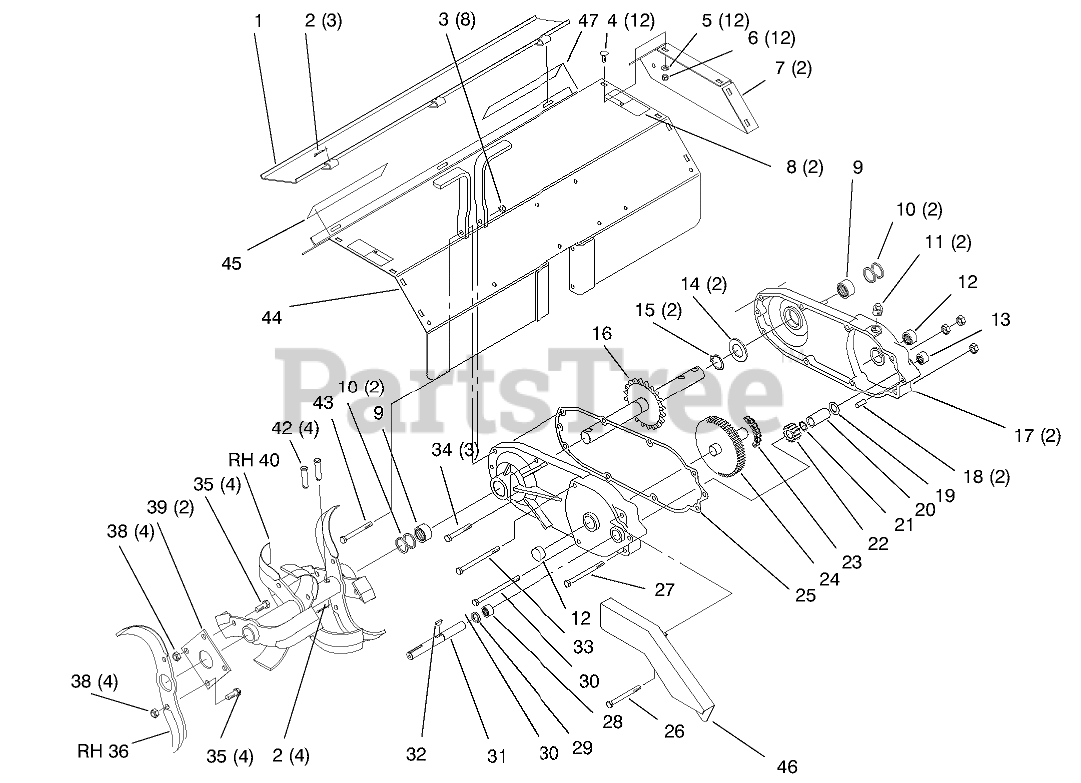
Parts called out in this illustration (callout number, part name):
1	GUARD ASM
2	PIN-COTTER
3	NUT-LOCK, NI
4	BOLT-CARR
5	WASHER-PLAIN
6	NUT-LOCK, NI
7	COVER-TINE END
8	DECAL-DANGER
9	BEARING-NEEDLE
11	PLUG-PIPE, SQH
12	BEARING-NEEDLE
13	BEARING-NEEDLE
14	WASHER
15	RING-RETAINING
16	TINE SHAFT ASM
17	GEAR CASE TILLER RED
18	PIN-ROLL
19	WASHER-THRUST
20	TUBE-SPACER
21	Ring-Snap
22	GEAR-PINION
23	CHAIN
24	GEAR AND SHAFT ASM
25	GASKET-TRANSMISSION
26	SCREW-HH
27	SCREW-HH
28	BEARING-NEEDLE
29	SEAL-OIL
30	SCREW-HH
31	SHAFT-INPUT
32	KEY-WOODRUFF
33	SCREW-HH
34	SCREW-HH
35	SCREW-HH
36	TINE-RH
37	TINE-LH
38	NUT-LOCK, NI
39	PLATE-TINE MOUNTING
40	RH TINE ASM
41	LH TINE ASM
42	PIN-CLEVIS
43	SCREW-HH
44	Shield W/Safety Decal
45	DECAL-ATTACHMENT
46	Guard-Tiller
47	DECAL-WORKHORSE
